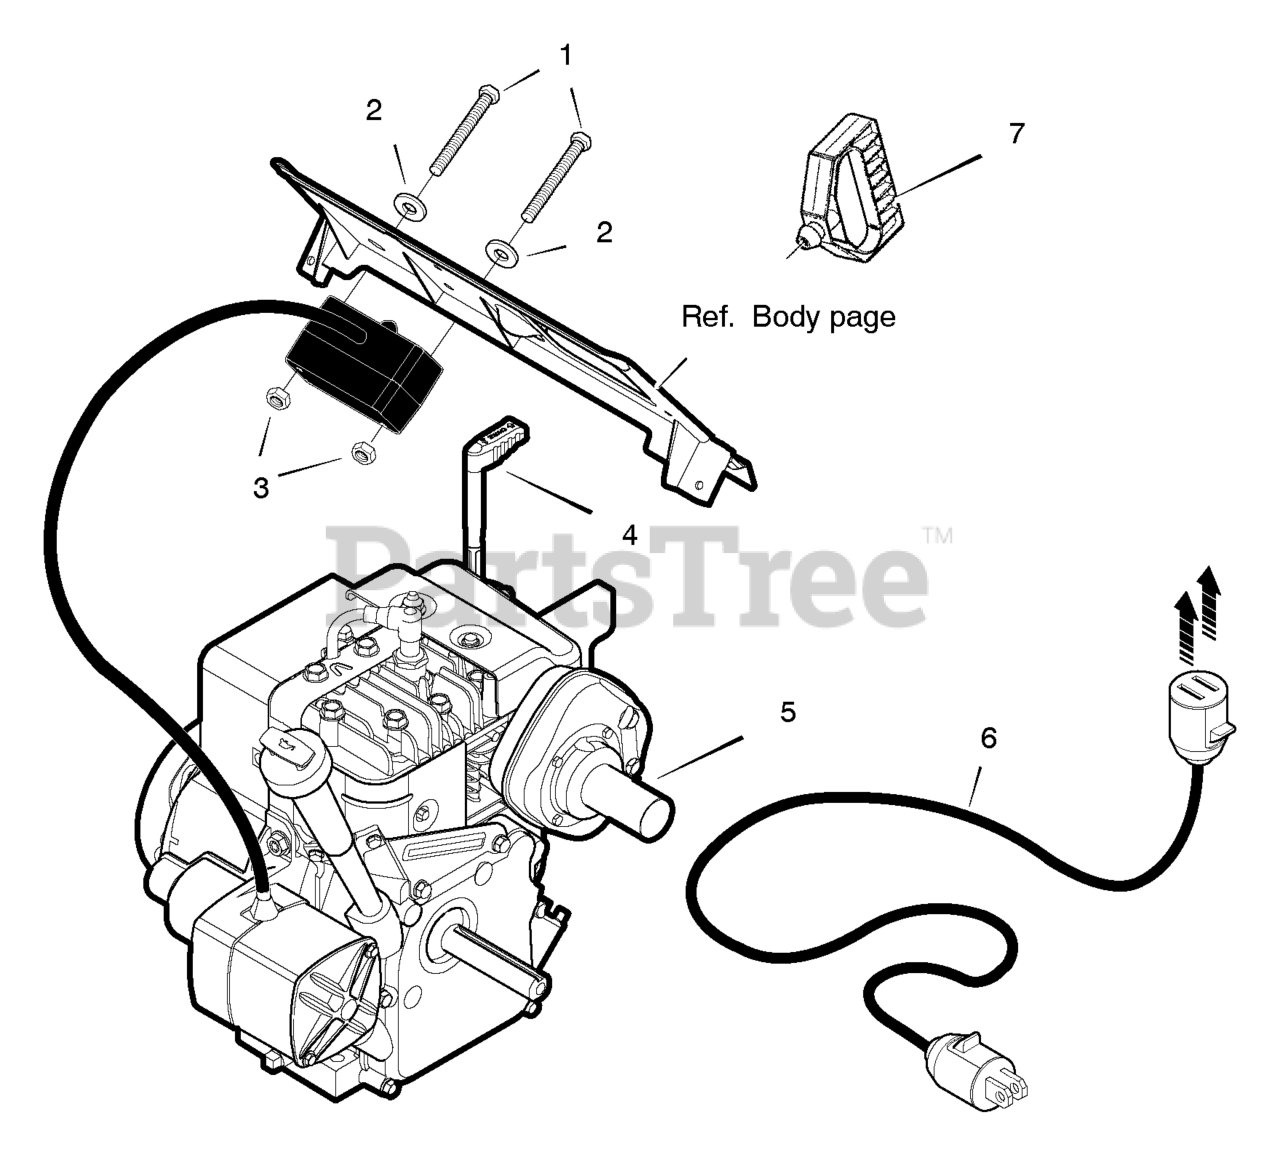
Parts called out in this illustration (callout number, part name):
1	Screw, No. 8-32 x 3.00
2	Washer
3	Nut, Keps No. 8
4	Lever, Choke*
5-1	Muffler *
5-2	Gasket, Muffler *
5-3	Bolt, Muffler *
5-4	Washer, Split Lock
5-5	Nut, Hex 5/16-18
5-6	Bolt, Hex 5/16-18
6	Cord, Extension
7	Grip, Mitten
